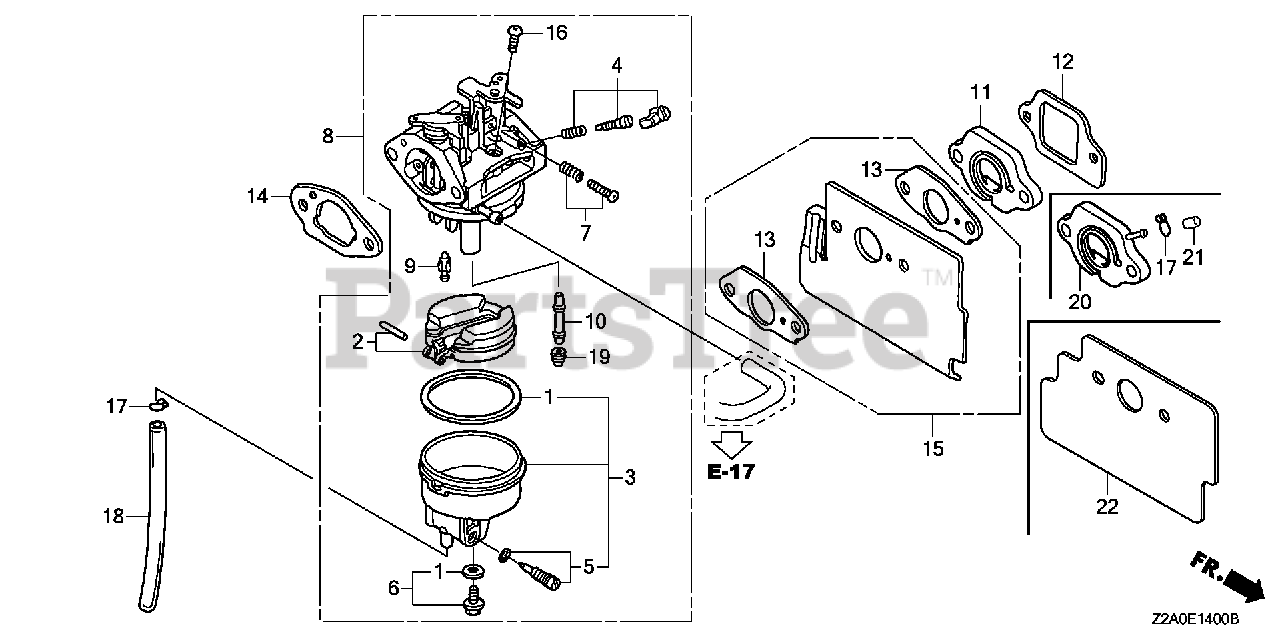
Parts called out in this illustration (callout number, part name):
1	GASKET SET
3	CHAMBER SET, FLOAT
4	SCREW SET (CARBURETOR NO.)
5	SCREW SET, DRAIN
6	SCREW SET
7	SCREW SET (THROTTLE STOP) (CARBURETOR NO.)
8	CARBURETOR ASSY. (BB61F C)
9	VALVE, FLOAT (CARBURETOR NO.)
10	NOZZLE, MAIN
11	INSULATOR, CARBURETOR
12	GASKET, INSULATOR
14	GASKET, CARBURETOR
16	SCREW, PAN (5X6)
17	CLIP, TUBE (B6.5)
18	BULK HOSE, VINYL (4X7X8000) (4X7X150)
19	JET, MAIN (#60)
19	JET, MAIN (#62)
19	JET, MAIN (#65)
22	GUIDE, AIR
